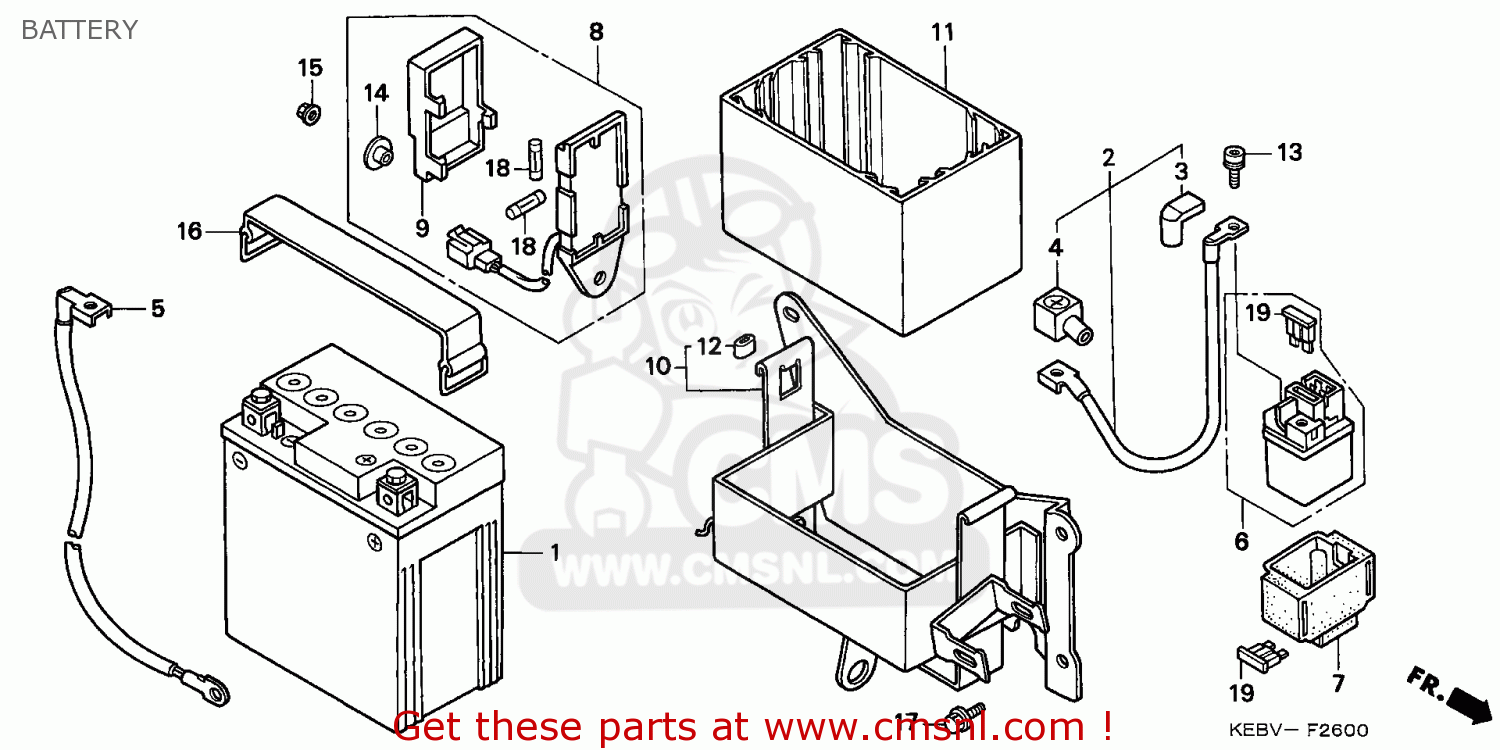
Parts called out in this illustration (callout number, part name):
1	BATTERY YTX7L-BS
2	CABLE,STARTER MAG
3	COVER A,STARTER M
4	COVER,BATTERY
5	CABLE,BATTERY EAR
6	SWITCH ASSY.,STAR
7	RUBBER,SHOCK
8	BOX ASSY.,FUSE
9	COVER FUSE
10	TRAY COMP. BATTERY
11	CUSHION,BATTERY
12	RUBBER TRAY BAT
13	BOLT,SOCKET,5X9
14	WASHER,CHAIN CASE
16	BAND D,BATTERY
17	BOLT,FLANGE,6X10
18	FUSE,A10
19	BLADE FUSE 20A
